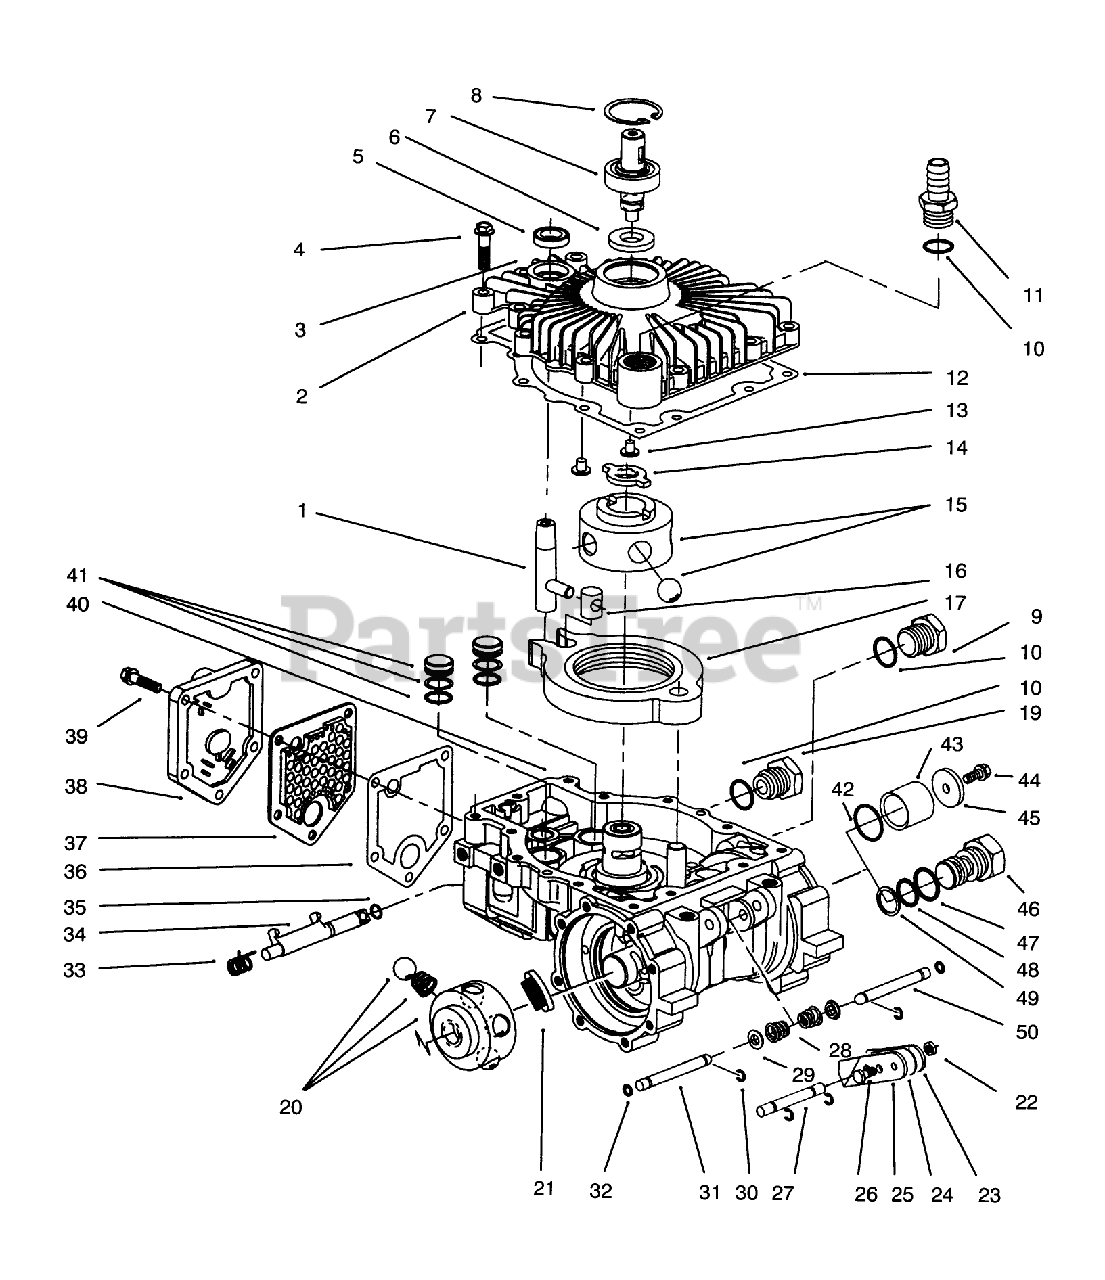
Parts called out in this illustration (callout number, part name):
1	CONTROL SHAFT
2	COVER ASM
3	COVER
5	SEAL-OIL
10	O-RING
17	CAM RING ASM
19	ROTOR BALL ASM
20	ROTOR BALL ASM
25	LH BRAKE LEVER
26	HEX HEAD SCREW
27	BRAKE SHAFT
31	PUSH ROD
32	QUAD SEAL
34	DUMP VALVE BRACKET
39	1/4-20 HEX HEAD SCREW
41	PISTON ASM
42	O-RING
43	CUP SEAL
45	WASHER
47	O-RING
48	O-RING
49	BACKUP RING
50	PUSH ROD
